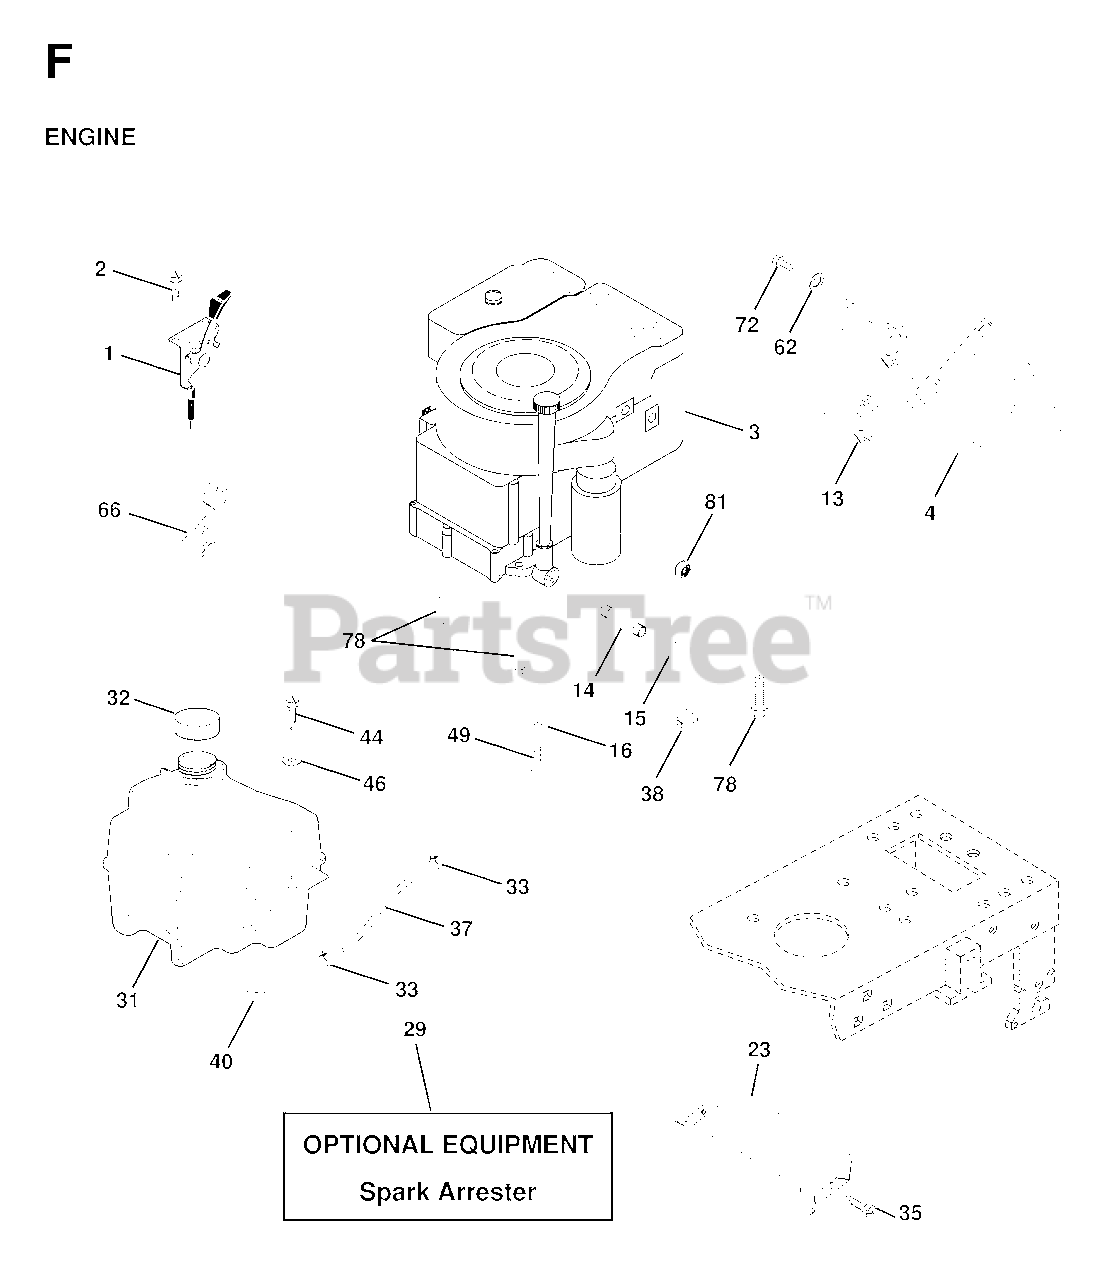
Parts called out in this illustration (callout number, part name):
1	CONTROL
2	SCREW LT
13	GASKET ENG
15	ELBOW
16	LOCKWASHER
23	PROTECTOR
29	ARRESTER SPARK (OPTIONAL)
31	FUEL TANK
32	FUEL CAP
33	HOSE CLAMP
35	SCREW
37	LINE.FUEL.20
40	GROMMET T
44	SCREW HEX CRT
49	SCREW GTV
62	LOCKWASHER
66	STOP THROTTLE
72	SCREW
78	SCREW
81	NUT FLANGE 1/4-20 STARTER NUT
